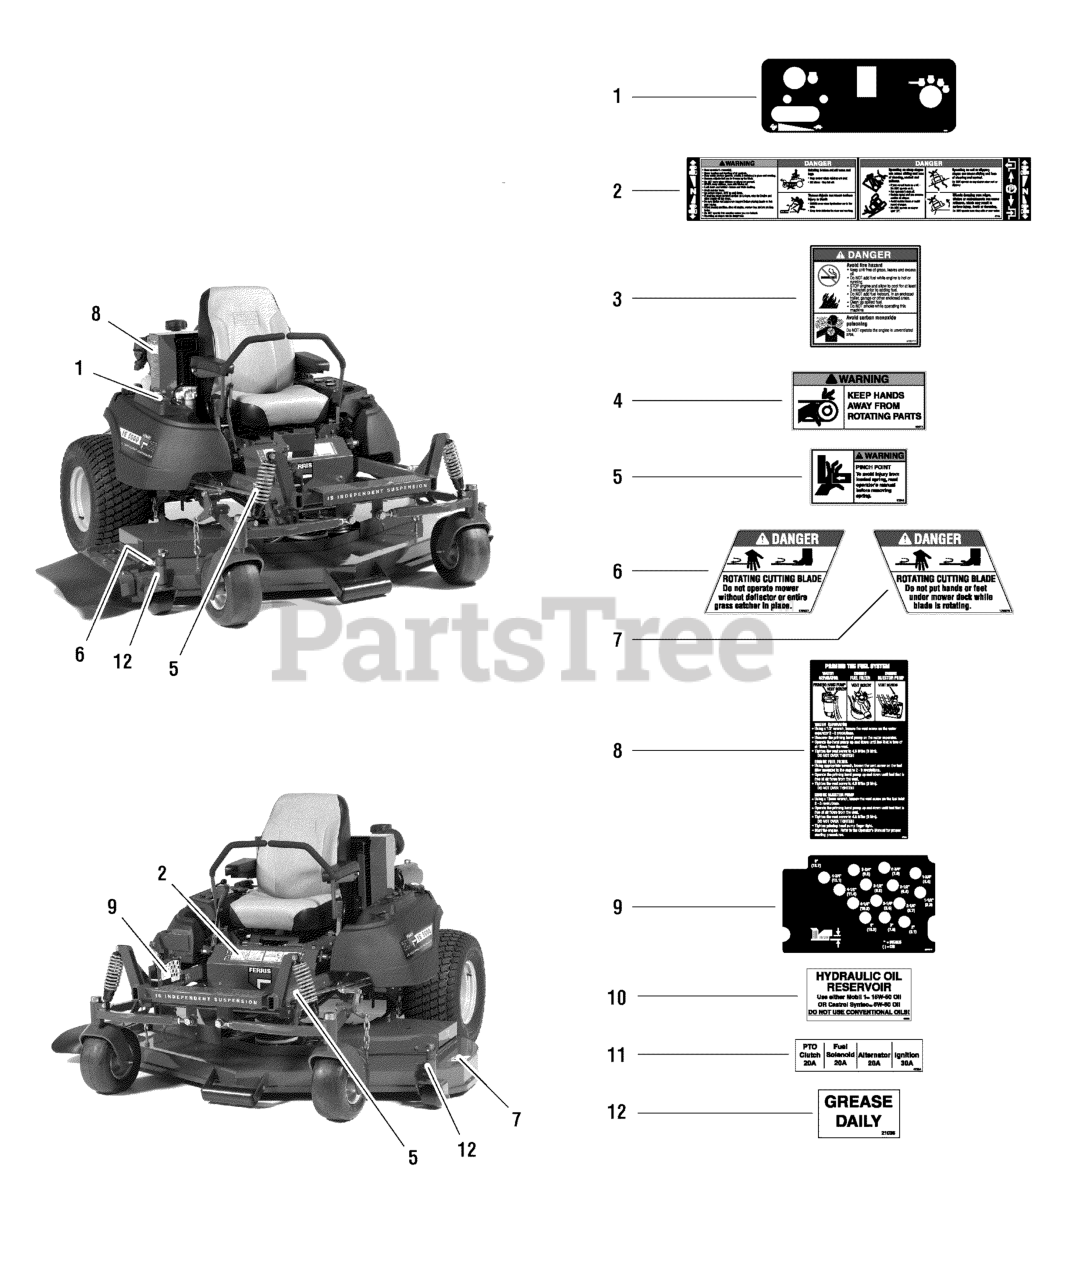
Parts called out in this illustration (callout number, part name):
1	DECAL, Control Panel
2	DECAL, Main
3	DECAL, Danger
4	DECAL, Warning
5	DECAL, Pinch Point
6	DECAL, Danger (Chute In Place)
7	DECAL, Danger (Hand Under Deck)
8	DECAL, Priming Instructions
9	DECAL, Deck Height
10	DECAL, Oil Reservoir
11	DECAL, Fuse Location
12	DECAL, Grease Daily
